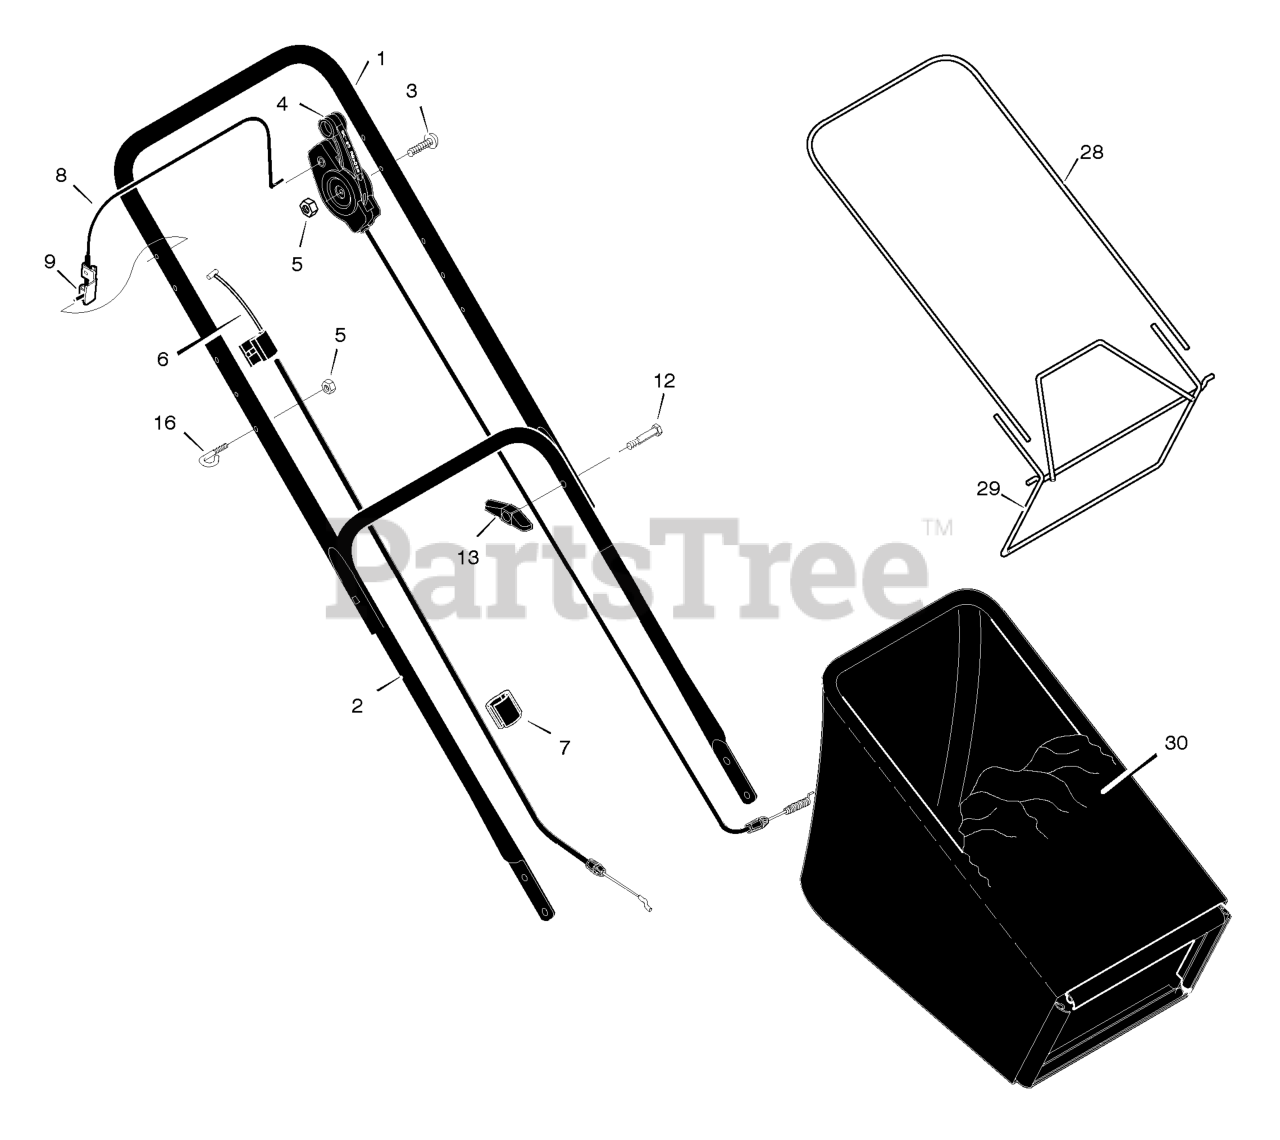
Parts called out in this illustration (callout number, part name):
1	Handle, Upper (Black)
2	Handle, Lower (Black)
4	Cable, Drive
5	Locknut
6	Cable, Stop
7	Fastener, Cable
8	Engine Stop Lever
9	Bracket, Stop Lever
13	Knob
16	Guide, Rope
28	Frame, Top
29	Frame Assembly
30	Bag, Cloth
